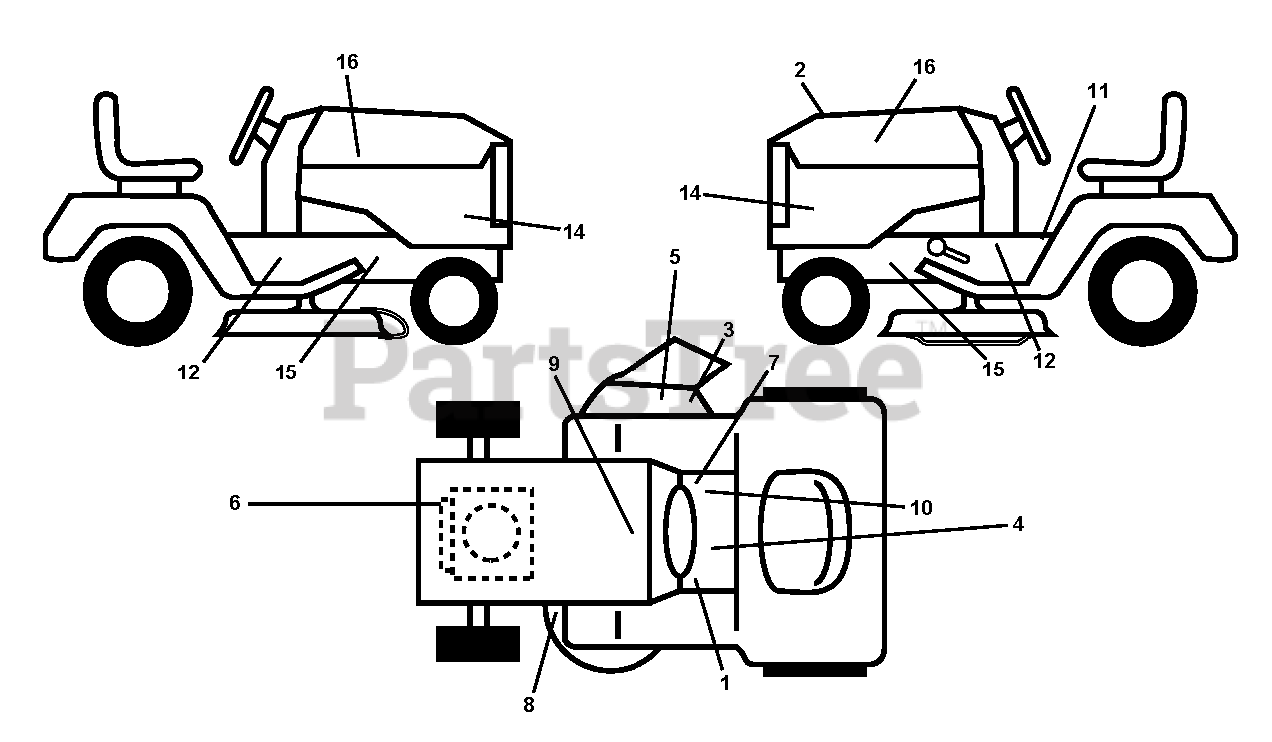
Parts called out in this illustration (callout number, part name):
1	DECAL
3	DECAL, DEFLECT WARNING
4	Decal, Fender 100 DB/CE
5	DECAL.INTERNATIONL.CUTFINGER
6	DECAL
7	DECAL PARK BRAKE
8	DECAL V BELT SCHEMATIC
9	DECAL BTRY SYMBOLS
10	DECAL
11	LABEL
16	RP.DECAL.BADGE.170MM.TEXTLOGO
